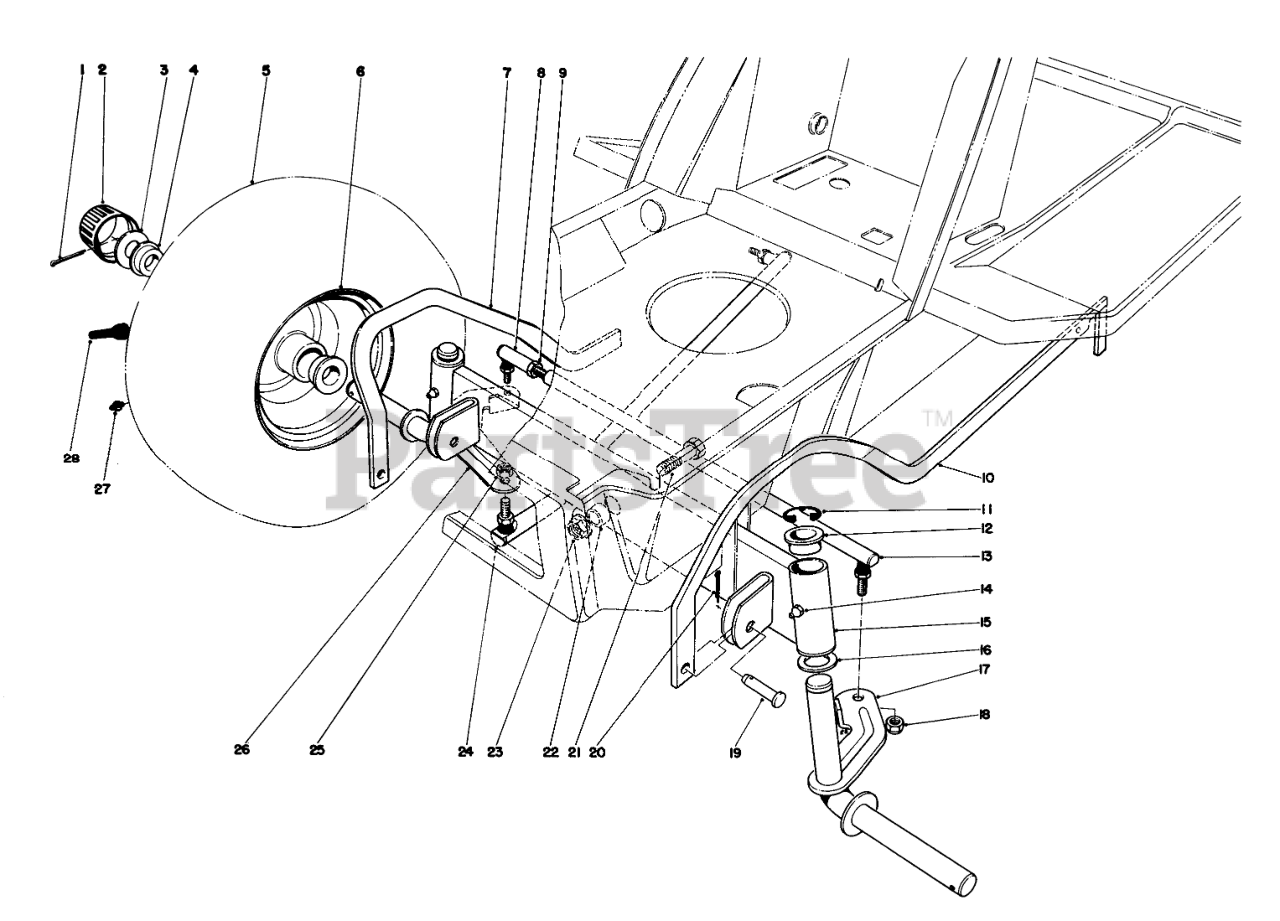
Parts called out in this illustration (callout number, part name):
1	PIN-COTTER
2	Cap-Hub
3	WASHER-PLAIN
4	Bearing
5	FRONT TIRE
6	FRONT RIM
7	R/F SCISSORS LINK WAB
8	JOINT-BALL
9	NUT-JAM
10	LF SCISSORS LINK WAB
11	E-Ring
12	BEARING-FLANGE
13	Tie Rod Steering (Incl. Ref. #8 & 9)
14	Fitting-Grease
15	Front Axle (Incl. Ref. #12)
16	WASHER-THRUST
17	LH SPINDLE WA PP
18	NUT-LOCK, NI
19	PIN-CLEVIS
20	PIN-COTTER
21	SCREW-HH
22	SPACER-AXLE, FRONT
23	NUT-HF
24	STEERING ARM B
25	NUT-HEX
26	RH SPINDLE WA PP
27	FITTING-GREASE
28	STEM-VALVE
